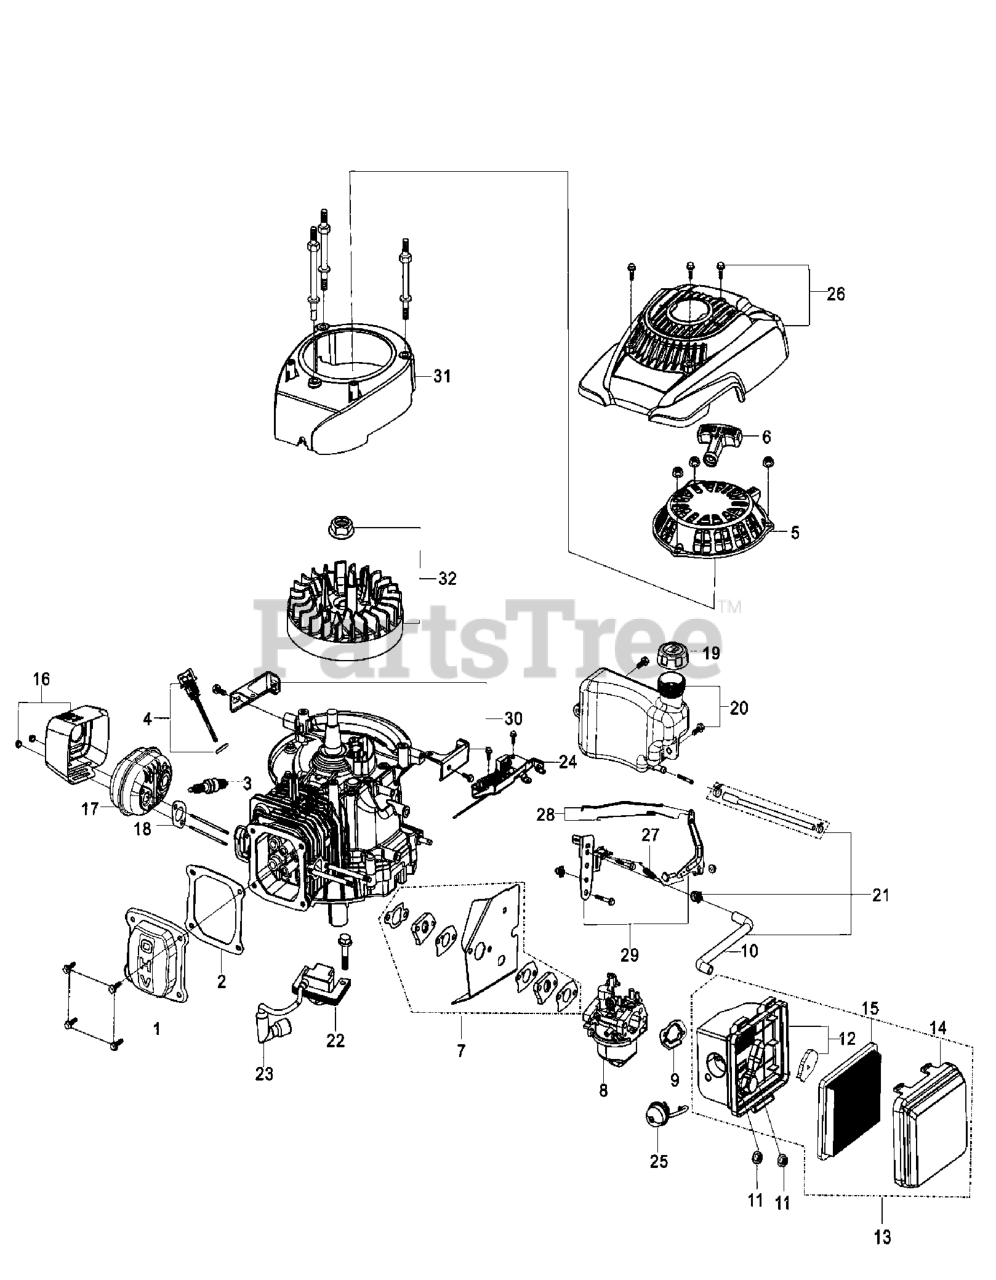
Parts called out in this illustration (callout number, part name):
1	COVER.SUBASSEMBLY.CYL.HEAD
2	GASKET.CYLIDER.HEAD.COVER
3	PLUG.SPARK
4	DIPSTICK.SUBASSEMBLY.OIL
5	STARTER.ASSY.RECOIL.RATO
6	HANDLE.RECOIL.STARTER.CABLE
7	SERVICE.KIT.GASKET/PLATE.RATO
8	CARBURETOR.ASSY.
9	GASKET.AIR.CLEANER
10	TUBE BREATHER
11	NUT FOR AIR CLEANER.INSTAL.
12	CASE.AIR.CLEANER
13	CLEANER.AIR
14	COVER.AIR.CLEANER.CASE
15	AIR.FILTER.RATO
16	MUFFLER.COVER
17	MUFFLER.ASM.W/HARDWARE.RATO
18	GASKET.EXHAUST.OUTLET
19	COVER.FUEL.TANK
20	FUEL.TANK ASSY.W/HARDWARE
21	SERVICE.KIT.W/FUEL HOSE
22	COIL.IGNITION
23	CAP.SPARK.PLUG.RATO
24	BRAKE.ASSY.
25	PRIMER.BULB.ASSY.W/HOSE&CLIP
26	SHROUD.W/HARDARE P.P.
27	SPRING.GOVENOR
28	THROTTLE.CONTROL.LEVER.SET
29	THROTTLE.CONTROL.ASSY.
30	FUEL TANK.ASSY.BRKTS.LF&RT
31	SHROUD.W/HARDARE P.P.
32	FLYWHEEL ASSY.
33	BLOWER.HOUSING.RATO.ENGINE
34	ENGINE.RATO.ASSY.W/O.SHROUD
